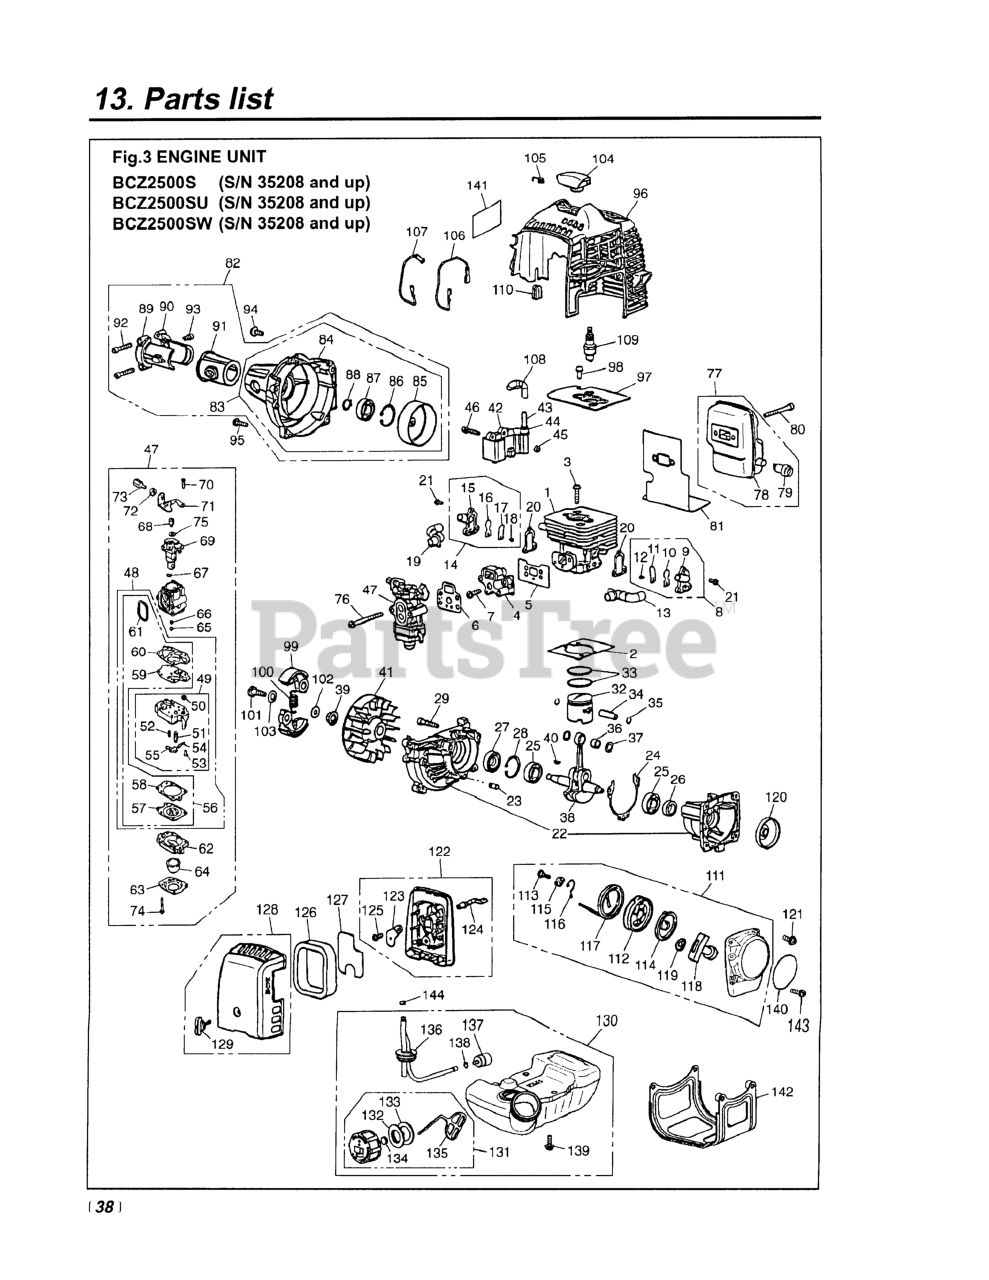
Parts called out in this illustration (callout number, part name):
1	CYLINDER (RPLS -12110)
2	GASKET, BASE
3	BOLT, M5 X 22
4	INSULATOR (RPLS. -13160/13161)
5	GASKET, INSULATOR
6	GASKET, CARBURETOR
7	SCREW, M5X20 (RPLS.1400-75510)
9	CASE VALVE
10	VALVE, REED
11	STOPPER
12	SCREW, M3 x 8
13	PIPE, AIR
16	VALVE, REED
17	STOPPER
18	SCREW, M3 x 8
19	PIPE, AIR (F)
20	GASKET, VALVE
21	SCREW
22	CRANKCASE-C
23	PIN
24	GASKET
25	BEARING
26	SEAL
27	SEAL, OIL (RPLS 1140-21220)
28	RING, SNAP, M28 x 1.2
29	BOLT, M5 X 30
32	PISTON
33	RING, PISTON
34	PIN, PISTON
35	RING, SNAP (RPLS 1101-41320)
36	BEARING (RPLS 1140-41330)
37	WASHER
38	CRANKSHAFT COMPLETE
40	KEY
41	ROTOR
42	COIL-A
43	CORD
44	CAP
45	SPACER (RPLS -71260)
46	BOLT, M4 x 22
49	PUMP BODY ASSEMBLY
50	SCREEN
51	VALVE, INLET
53	SCREW
54	PIN
55	LEVER
57	DIAPHRAGM
58	GASKET, DIAPHRAGM
59	DIAPHRAGM, PUMP
60	GASKET, PUMP
61	RING
62	BODY, PURGE
63	COVER, PUMP
64	PUMP, PRIMING
65	JET (REPLACES 4810-81250)
66	RING, O
67	RING
68	SWIVEL
69	VALVE ASSY
70	SCREW
72	NUT, CABLE ADJUSTER
73	SCREW, CABLE ADJUSTER
74	SCREW
75	WASHER
76	SCREW, M5 x 60
77	MUFFLER ASSEMBLY
78	MUFFLER (REPLACES -15110)
79	ARRESTER
80	BOLT, M5 x 50
81	GASKET (RPLS T1501-15210)
82	COVER-A (USE -31002)
83	COVER-C (USE -31102)
84	COVER, FAN (USE -31111)
86	RING, SNAP, M28 x 1.2
88	RING, SNAP (RPLS 3130-13270)
89	BRACKET (A) (RPLS -31210)
90	BRACKET (B) (REPLACES -31220)
91	CUSHION
92	BOLT, M5 X 30
93	BOLT (USE 3310-31720)
94	SCREW
95	SCREW, M5X20 (RPLS.1400-75510)
96	COVER, ENGINE (RPLS -32110)
97	PLATE, CYLINDER
98	SCREW, M5 X 10
99	SHOE
100	SPRING
101	BOLT
102	WASHER, FLAT (USE 182303)
103	WASHER (RPLS -51241)
105	SPRING
106	CORD (BLACK)
107	CORD, EARTH (RED)
108	TUBE
110	GROMMET
111	RECOIL ASSEMBLY
112	REEL
113	SCREW
114	SPRING, SPIRAL
115	COLLAR
116	ARM
117	ROPE (REPLACES 4500-75160)
118	KNOB (RPLS -75420)
119	PLATE, STOPPER
120	PULLEY
121	SCREW
122	BODY ASSEMBLY
123	PLATE, CHOKE
124	LEVER, CHOKE
125	SCREW (REPLACES 50030272)
126	ELEMENT
127	SCREEN
128	COVER ASSEMBLY
129	KNOB (RPLS -82220)
131	CAP ASSY (RPLS -85201)
132	HOLDER (REPLACES -85230)
133	PACKING
134	FILTER
135	STOPPER
136	PIPE COMPLETE
137	FILTER (RPLS 1850-85300)
138	CLIP (REPLACES 2841-31280)
139	SCREW
140	LABEL, RECOIL
141	LABEL, COVER (RPLS -31130)
142	GUARD (RPLS 4810-31911)
143	SCREW, M5 x 25
144	CLIP
